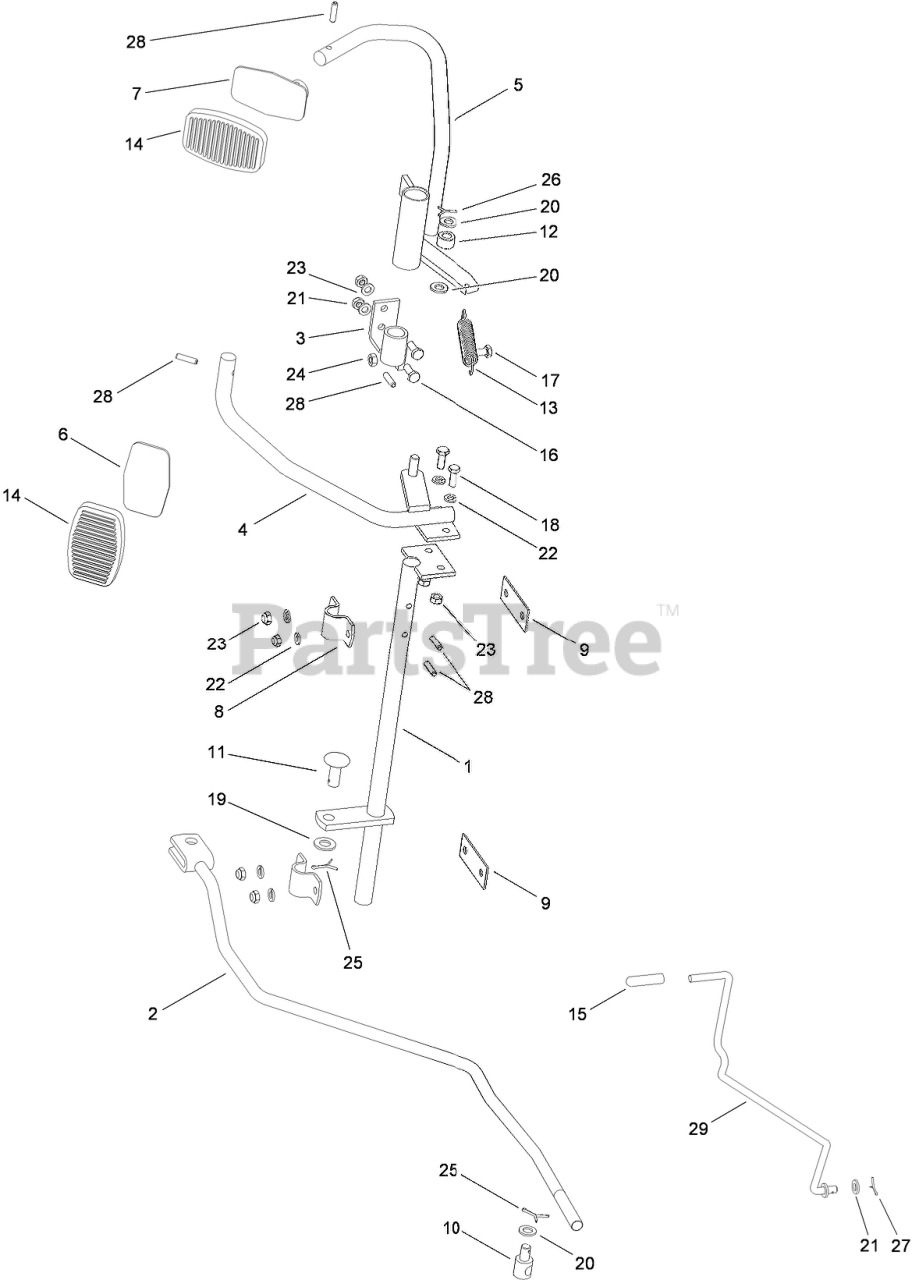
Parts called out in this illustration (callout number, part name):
1	SHAFT-PIVOT
2	ROD-LINKAGE
3	BRACKET-PEDAL SUPPORT
4	PEDAL-TRAVEL, FORWARD
5	PEDAL-TRAVEL, REVERSE
6	PEDAL-PAD, FORWARD
7	PEDAL-PAD
9	SPACER
12	Roller
13	SPRING
14	PAD-PEDAL
15	CAP-BYPASS LEVER, HYDRO
16	SCREW-HH
17	SCREW-HH
18	SCREW-HSH
19	WASHER-FLAT
20	WASHER-PLAIN
21	WASHER
22	WASHER-SPRING
23	NUT-LOCK
24	NUT-HEX
25	PIN-COTTER
26	PIN-COTTER
27	PIN-COTTER
28	PIN-SPRING
29	ROD-LEVER, BYPASS
